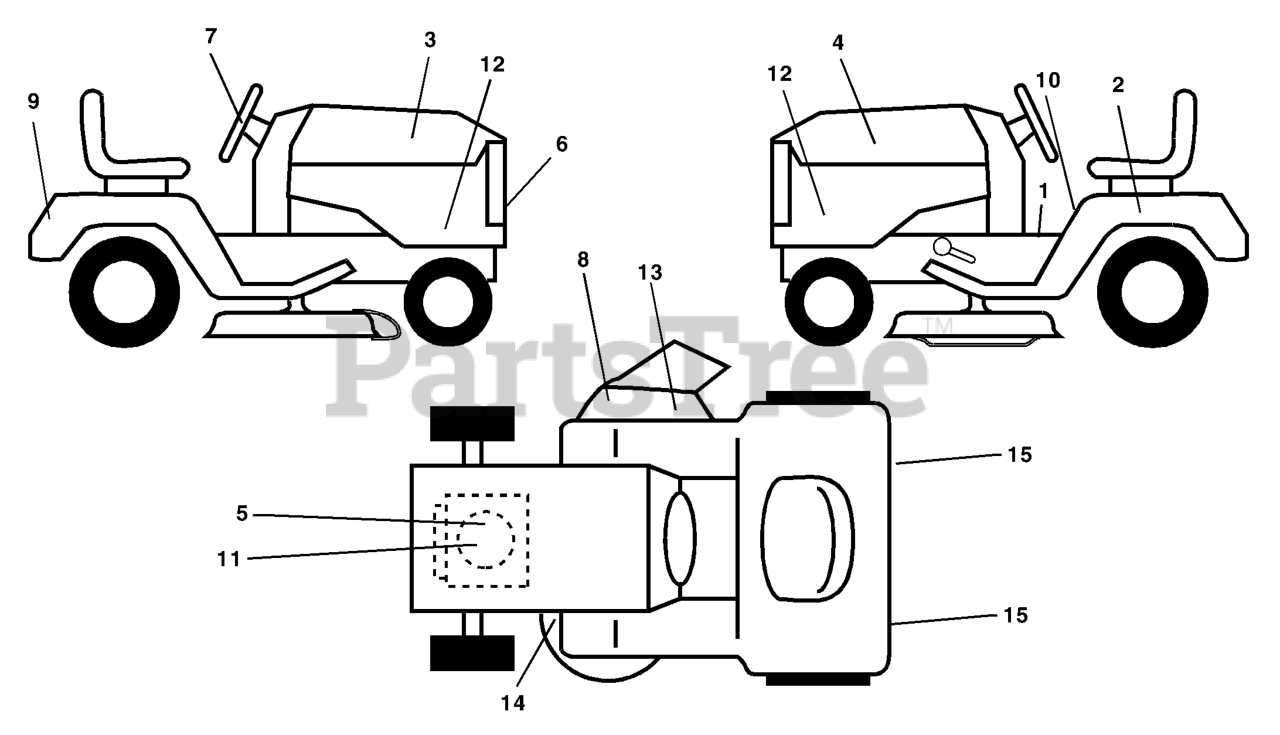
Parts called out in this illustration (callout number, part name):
2	DECAL BTRY SYMBOLS
5	DECAL HP ENGINE
6	DECAL.GRILLE.HUSQ
7	DECAL.WHEEL.STEERING.HUSQ.PERM
8	DECAL.WARN.KEEP.HAND.AWAY
9	DECAL, FENDER
10	DECAL FENDER DANGER
11	DECAL, ENGINE LOGO
12	DECAL, HOOD SIDE
13	DECAL DECK "B" 42"
14	DECAL V BELT SCHEMATIC
15	REFLECTOR-TAIL YT
